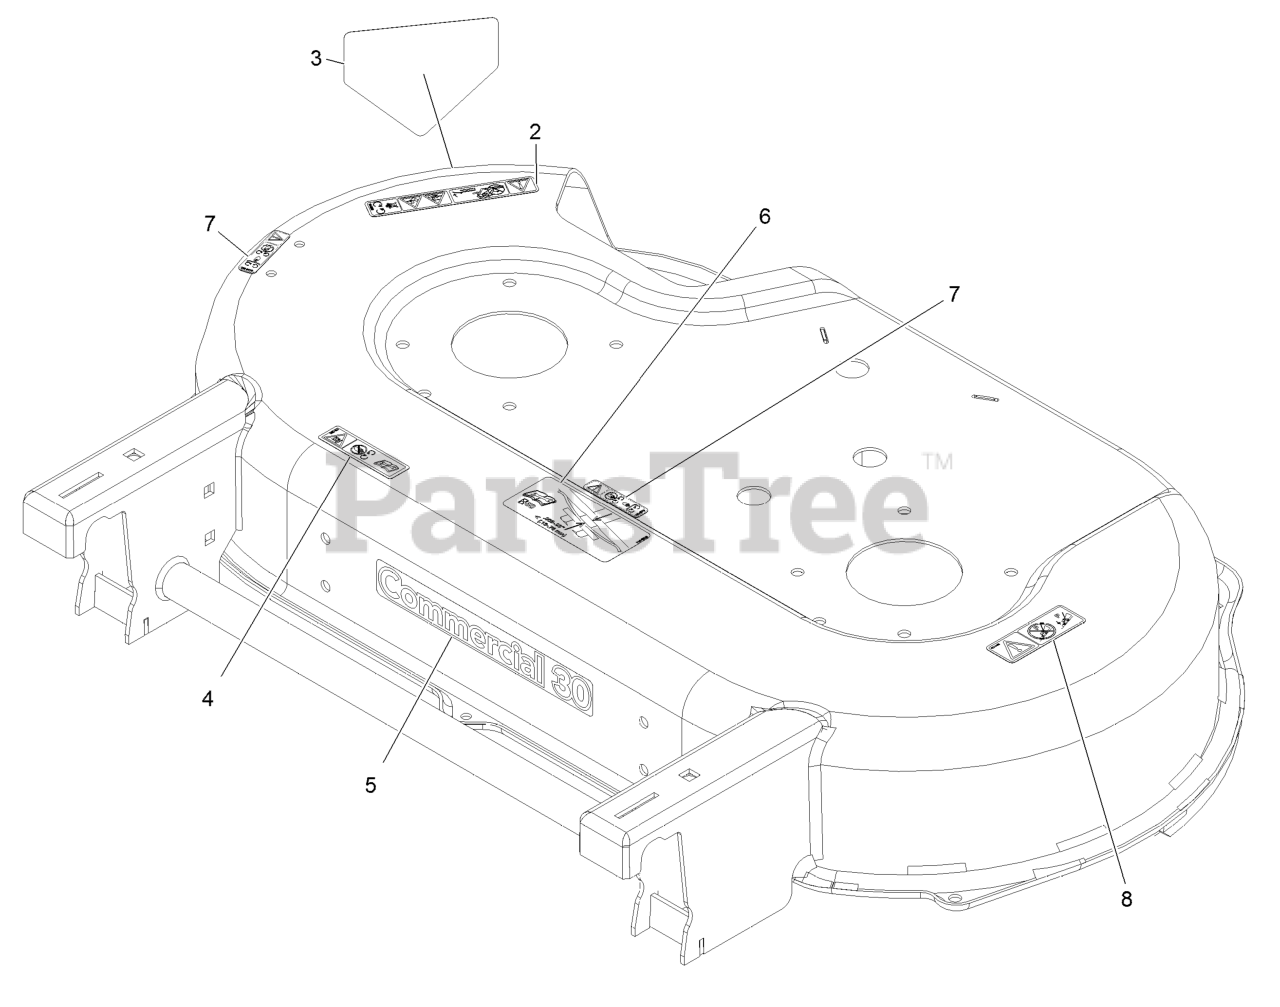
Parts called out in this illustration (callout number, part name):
2	DECAL-DANGER
3	DECAL-DANGER
4	DECAL-WARNING
5	DECAL-COMMERCIAL 30
7	DECAL-WARNING
8	DECAL-WARNING, BLOCK
